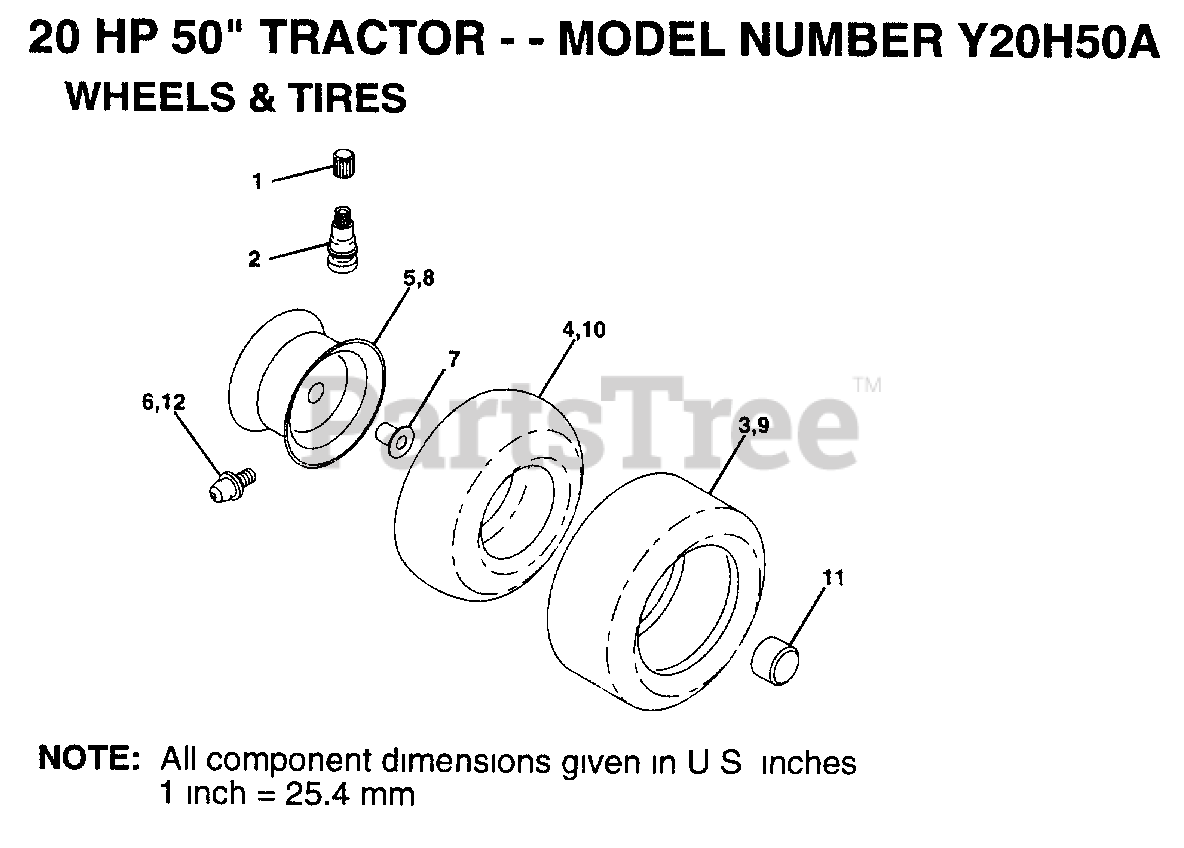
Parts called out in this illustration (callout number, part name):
1	VALVE CAP
2	VALVE STEM LT
4	TUBE.16X6.5/7.5-8
5	"RIM ASM 8"" FRT"
6	ZERK FITTING M
7	"FLANGE, BEARING"
8	"RIM ASM 12"" REAR"
10	TUBE.23X8/10-12
11	HUB CAP
12	FITTING LT
